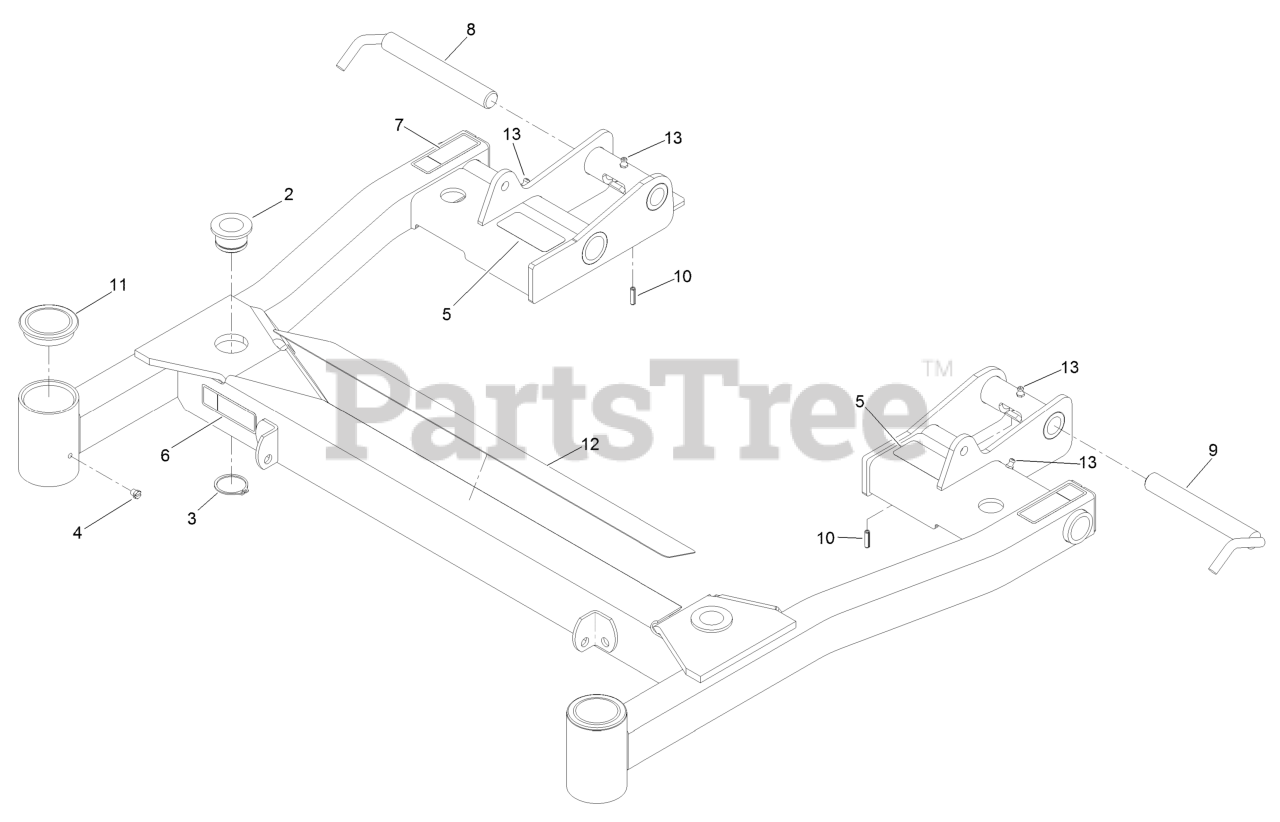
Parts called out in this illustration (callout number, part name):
2	BUSHING-SUPPORT, DECK
3	RING-RETAINING
5	DECAL-WARNING
6	DECAL-DANGER
7	DECAL-WARNING, FOLDING DE
8	LOCK-DECK, RH
9	LOCK-DECK, LH
10	PIN-SPRING
11	CAP-GREASE
12	PAD-SKID, ANTI
13	FITTING-GREASE
